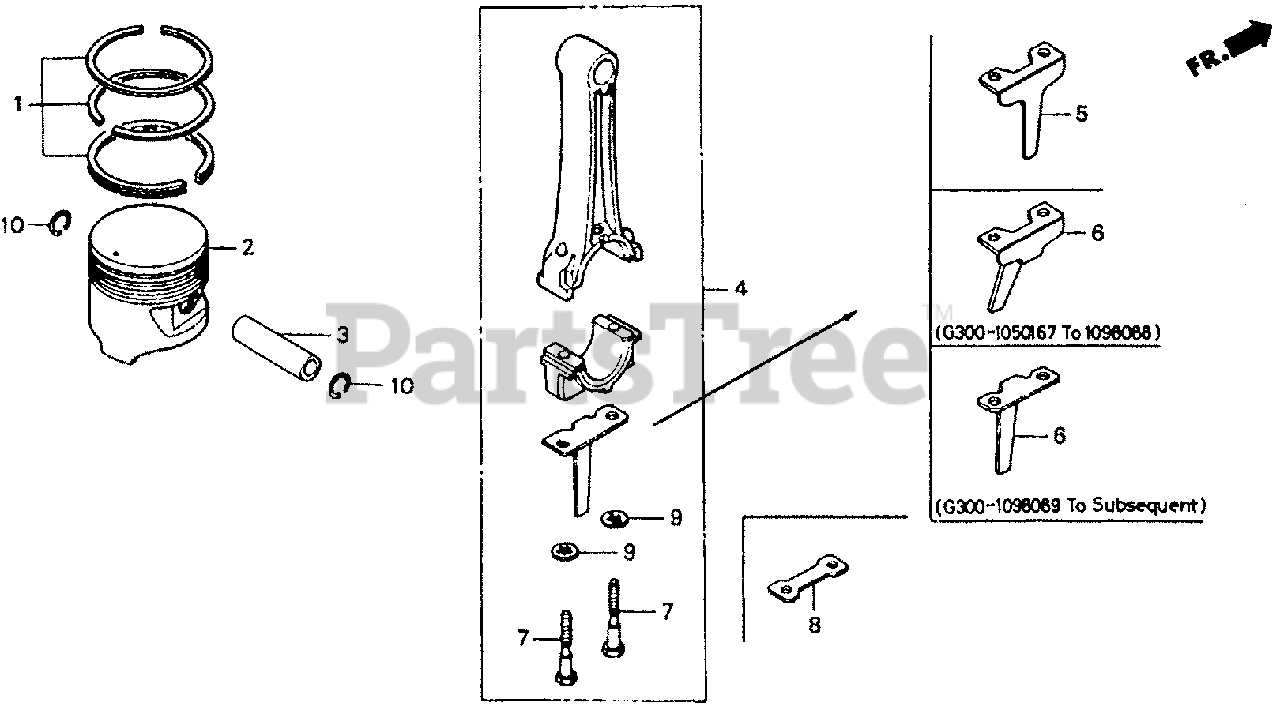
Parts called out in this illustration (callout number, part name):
1	RING SET, PISTON
1	RING SET, PISTON (STD)
1	RING SET, PISTON (OS 0.25)
1	RING SET, PISTON (OS 0.50)
1	RING SET, PISTON (0.75)
2	PISTON (STD)
2	PISTON (OS 0.25)
2	PISTON (OS 0.50)
2	PISTON (0.75)
3	PIN, PISTON
4	ROD ASSY., CONNECTING
4	ROD ASSY., CONNECTING (UNDER SIZE)
5	DIPPER, CONNECTING ROD
6	DIPPER, CONNECTING ROD
7	BOLT, CONNECTING ROD (7MM)
7	BOLT, CONNECTING ROD (8MM) (NOT AVAILABLE)
7	BOLT, CONNECTING ROD (8MM)
8	WASHER, LOCK (7MM)
9	WASHER, LOCK (7MM)
10	CLIP, PISTON PIN (16MM)
